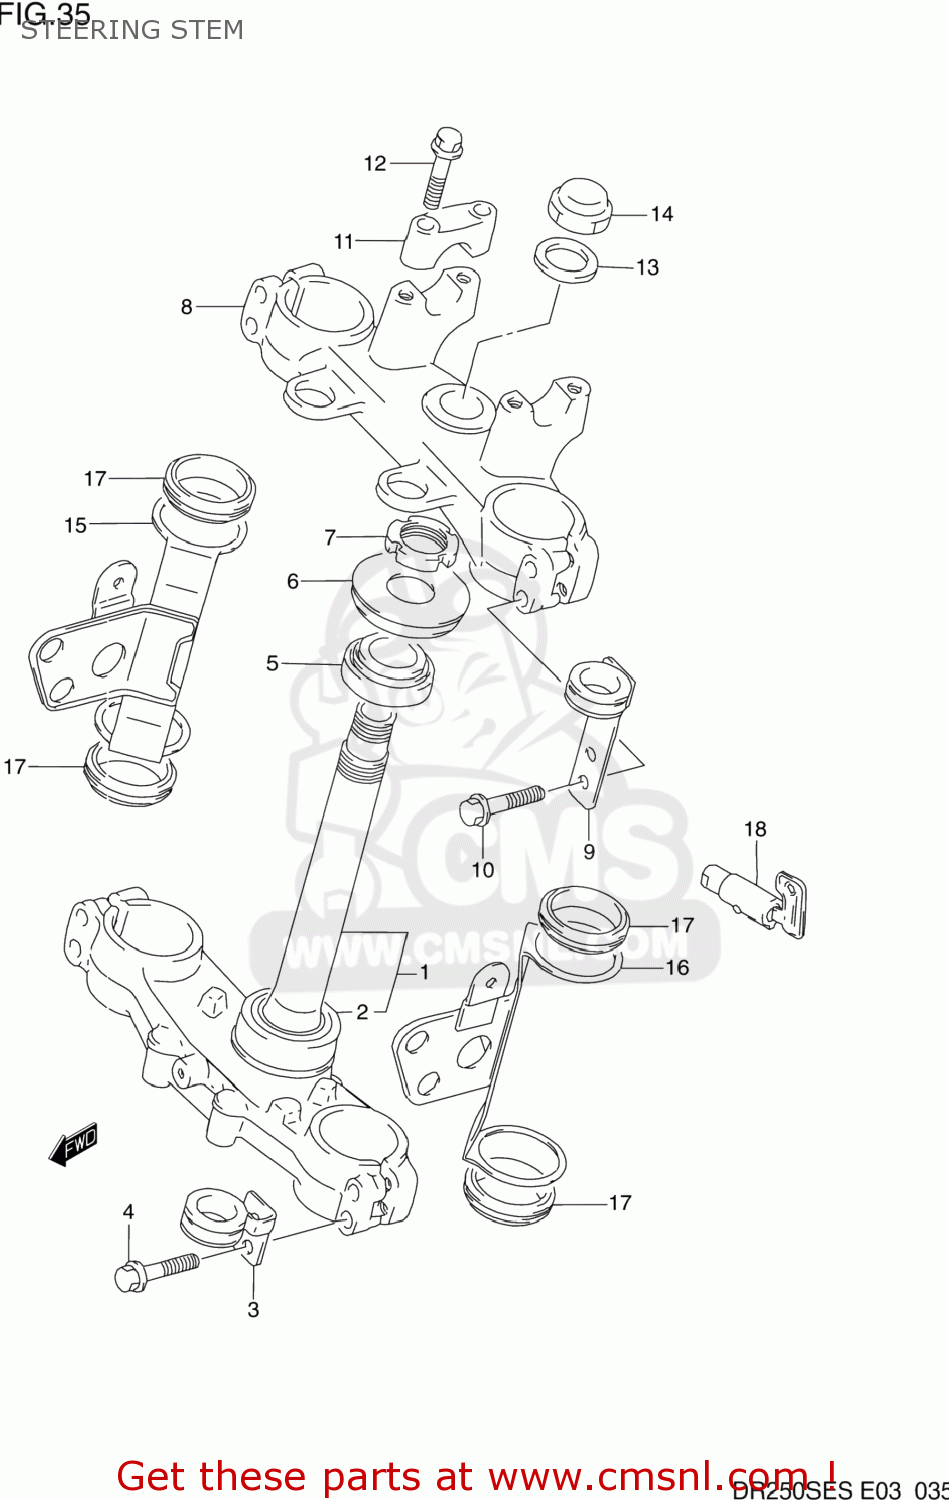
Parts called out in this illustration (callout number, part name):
1	STEM,STEERING
2	BEARING(30X55X17)
3	GUIDE,CABLE LWR,L
4	BOLT
5	TAPER,ROLLER BEARING
6	SEAL,STEERING UPR DUST
7	NUT,STEERING STEM
8	HEAD,STEERING STEM
9	GUIDE,CABLE,LEFT,UPPER
10	BOLT
11	HOLDER,HANDLE UPR
12	BOLT
13	WASHER
14	NUT,CAP
15	BRACKET,HEADLAMP HOUSING,R
16	BRACKET,HEADLAMP HOUSING,L
17	DAMPER,HEADLAMP HSG BRACKET
18	LOCK ASSY,STEERING(NEIMAN)
